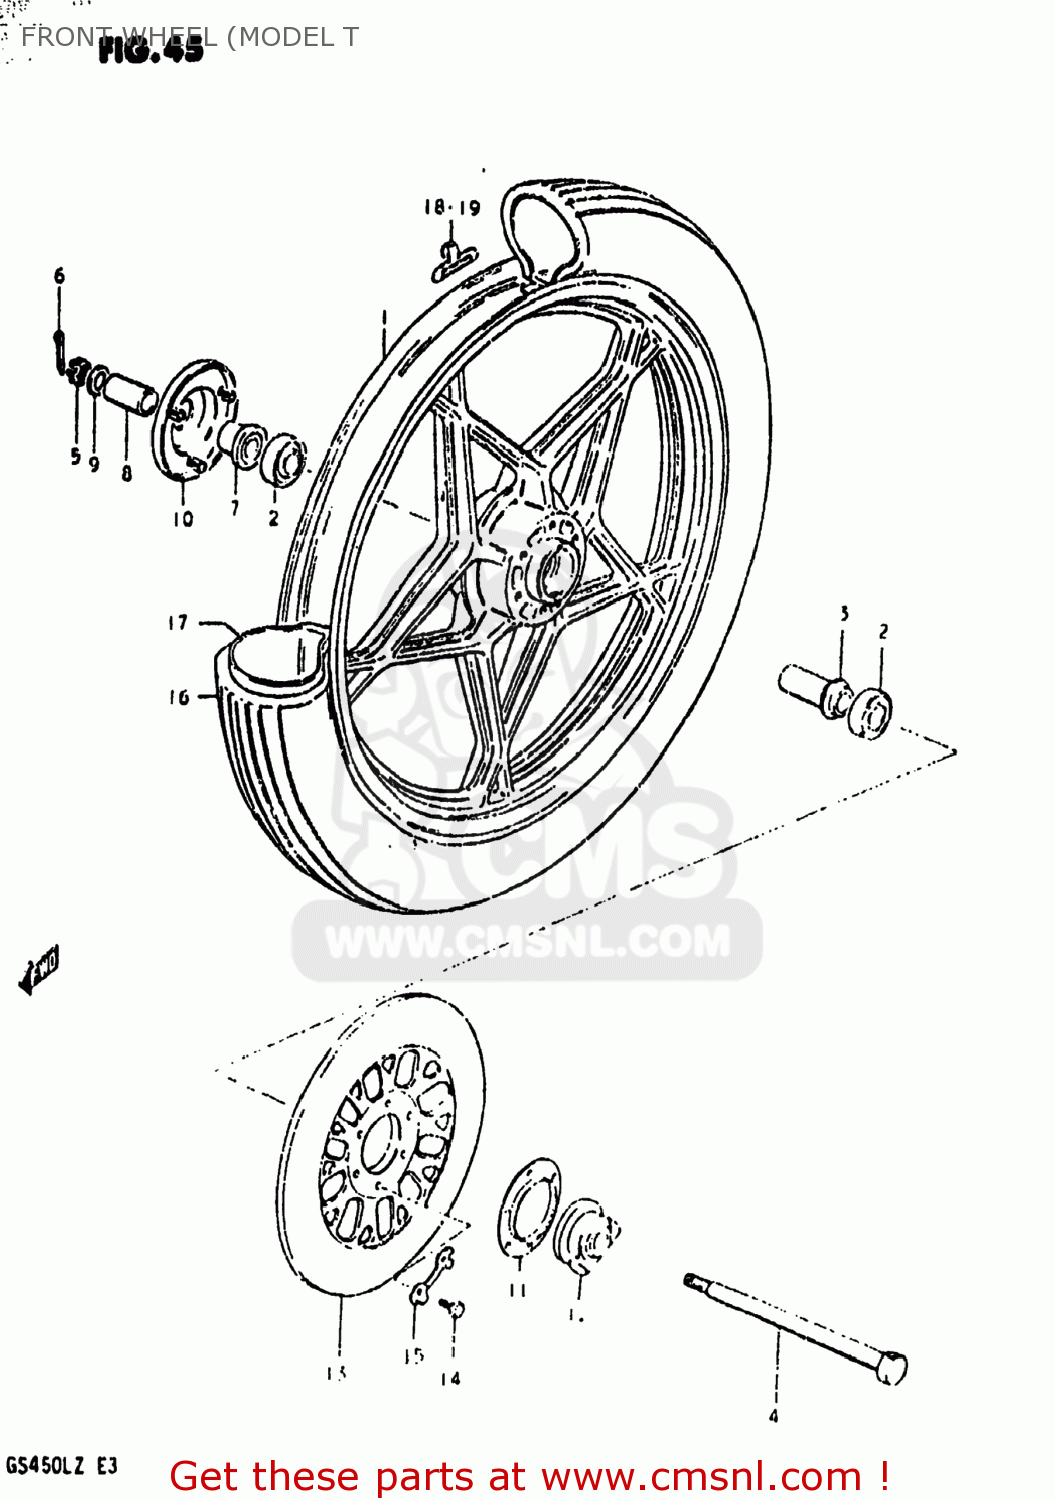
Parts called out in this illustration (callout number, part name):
1	FR CAST WHEEL 1
2	BEARING
3	SPACER,FR HUB BEARING
4	AXLE,FRONT
5	NUT 12MM
6	COTTER PIN
7	SPACER,FR HUB BEARING,R
8	SPACER(15X22X30)
9	WASHER
10	COVER,FR HUB,R
11	DUST SEAL,SPEEDOMETER GEAR BOX
12	BOX ASSEMBLY,SPEEDOMETER GEAR
13	DISC,FR BRAKE
14	BOLT(8X25)
15	WASHER
16	TIRE,FRONT
17	TUBE,INNER
18	BALANCER,WHEEL
19	BALANCER,WHEEL
